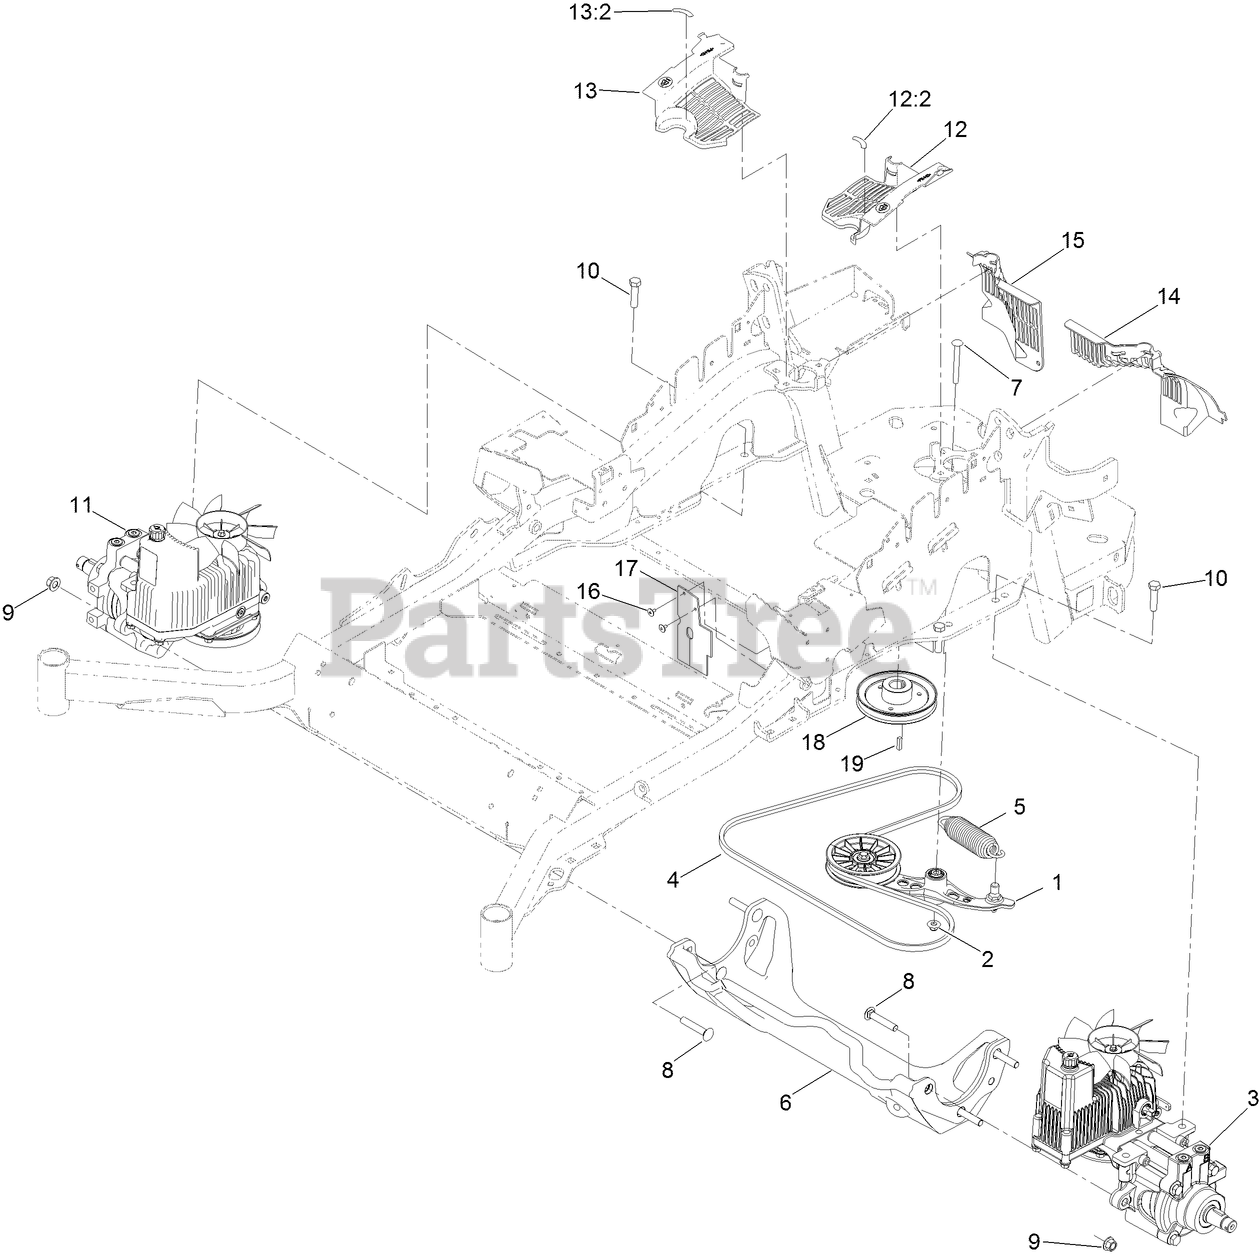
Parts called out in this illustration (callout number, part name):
1	PUMP IDLER ASM
2	NUT-FLANGE, NI
3	LH HYDRO ASM (16CC W/ SHOCK)
4	BELT
5	SPRING-EXTENSION
6	CRADLE-HYDRO
7	BOLT-SHOULDER, CARRIAGE
8	SCREW-CARR
9	NUT-LOCK
10	SCREW-HH
11	RH HYDRO ASM (16CC W/ SHOCK)
12	LH HYDRO GUARD ASM
12:2	DECAL-OIL, HYDRO
13	RH HYDRO GUARD ASM
13:2	DECAL-OIL, HYDRO
14	GUARD-HYDRO REAR, LH TRIM
15	GUARD-HYDRO, REAR (RH)
16	RIVET-POP
17	DEFLECTOR-AIR FLOW
18	SHEAVE
